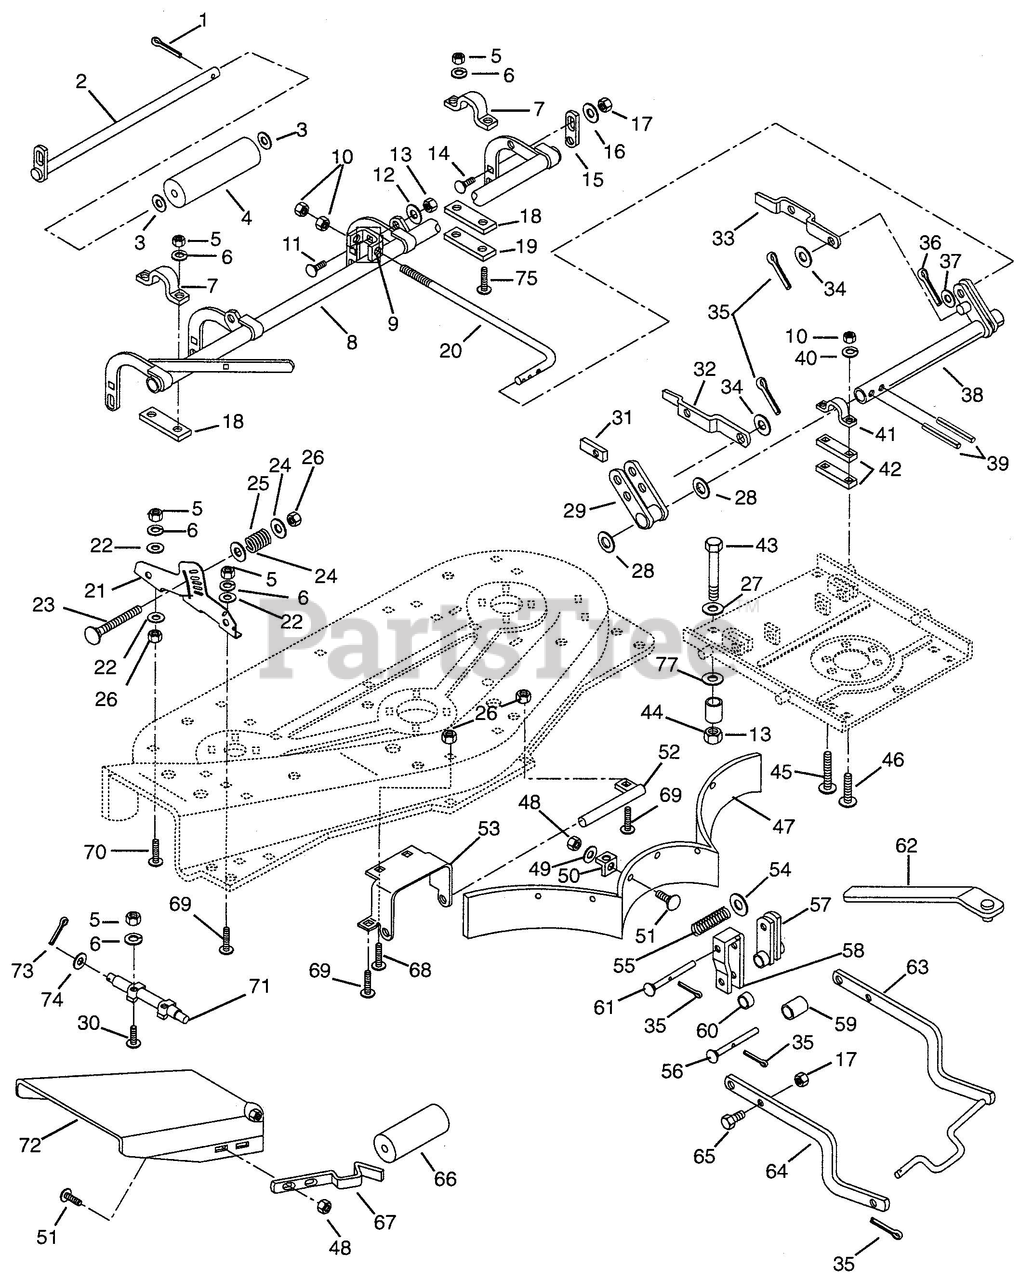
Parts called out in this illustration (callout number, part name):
1	PIN-COTTER .18 X 1.0
2	ROLLER SHAFT
3	WASHER-FLAT-STEEL .656 X 1.31 X .095
5	NUT-HEX .31-18
6	WASHER-LOCKING .312
7	CLAMP
8	ROLLER FRAME
10	NUT .50-13
11	BOLT-ROUND HEAD SQUARE NECK .50-13 X 1.25
12	WASHER-FLAT-STEEL .505 X .880 X .062
13	NUT-LOCKING-CENTER .500-13
14	BOLT-ROUND HEAD SQUARE NECK .38-16 X 1.00
16	WASHER-FLAT-STEEL .438 X 1.0 X .083
17	NUT-LOCKING .375-16
18	ADJUSTMENT PLATE
19	ADJUSTMENT PLATE
20	ADJUSTMENT ROD
21	QUADRANT
22	WASHER-FLAT-STEEL .323 X .625 X .062
23	BOLT-ROUND HEAD SQUARE NECK .31-18 X 1.75
24	WASHER-FLAT-STEEL .38 X .875 X .083
25	SPRING-COMPRESSION .063 X .53 X 1.187
26	NUT-LOCKING .312-18
27	WASHER-FLAT-STEEL .531 X 1.06 X .095
28	WASHER-FLAT-STEEL .765 X 1.250 X .062
29	FRONT HANGER LINK
30	BOLT-HEX .31-18 X .75 GRADE 5
31	WEAR PLATE
32	LEVELING LEVER RH
33	LEVELING LEVER LH
34	WASHER-FLAT-STEEL .511 X 1.44 X .125
35	PIN-COTTER .12 X 1.0
36	PIN-COTTER .18 X 2.0
37	WASHER-FLAT-STEEL .50 X 1.25 X .083
38	FRONT HANGER
39	PIN-ROLL .250 X 1.25
40	WASHER-LOCKING .500 X .151
43	BOLT-HEX .50-13 X 2.75 GRADE 5
44	SPACER PIVOT
45	BOLT-ROUND HEAD SQUARE NECK .50-13 X 1.75
46	BOLT-ROUND HEAD SQUARE NECK .50-13 X 1.50
47	BAFFLE
48	NUT-LOCKING-CENTER .250-20
49	WASHER-FLAT-STEEL .281 X .62 X .065
50	BAFFLE TAB
51	BOLT-ROUND HEAD SQUARE NECK .25-20 X .50
52	ROLLER SHAFT
53	BRACKET-ROLLER
54	WASHER-FLAT-STEEL .531 X 1.06 X .095
55	SPRING-COMPRESSION .62 X .68 X 1.75
56	CLEVIS PIN
57	ARM
58	SUPPORT CHANNEL
61	CLEVIS PIN
63	MOWER HANGER
64	HANGER ARM
65	BOLT-HEX .38-16 X 1.00 GRADE 5
67	FLAT SPRING
68	BOLT-ROUND HEAD SQUARE NECK .312-18 X .62
69	BOLT-ROUND HEAD SQUARE NECK GRADE 5 .31-18 X .75
70	BOLT-ROUND HEAD SQUARE NECK .31-18 X 2.75
71	PIN-HINGE
72	CHUTE EXTENSION
73	PIN-COTTER .09 X .75
74	WASHER-FLAT-STEEL .406 X .812 X .065
75	BOLT-ROUND HEAD SQUARE NECK .31-18 X 1.50 GRADE 5
76	NUT-LOCKING-HEX .50-13
77	WASHER-FLAT-STEEL .505 X 1.00 X .062
